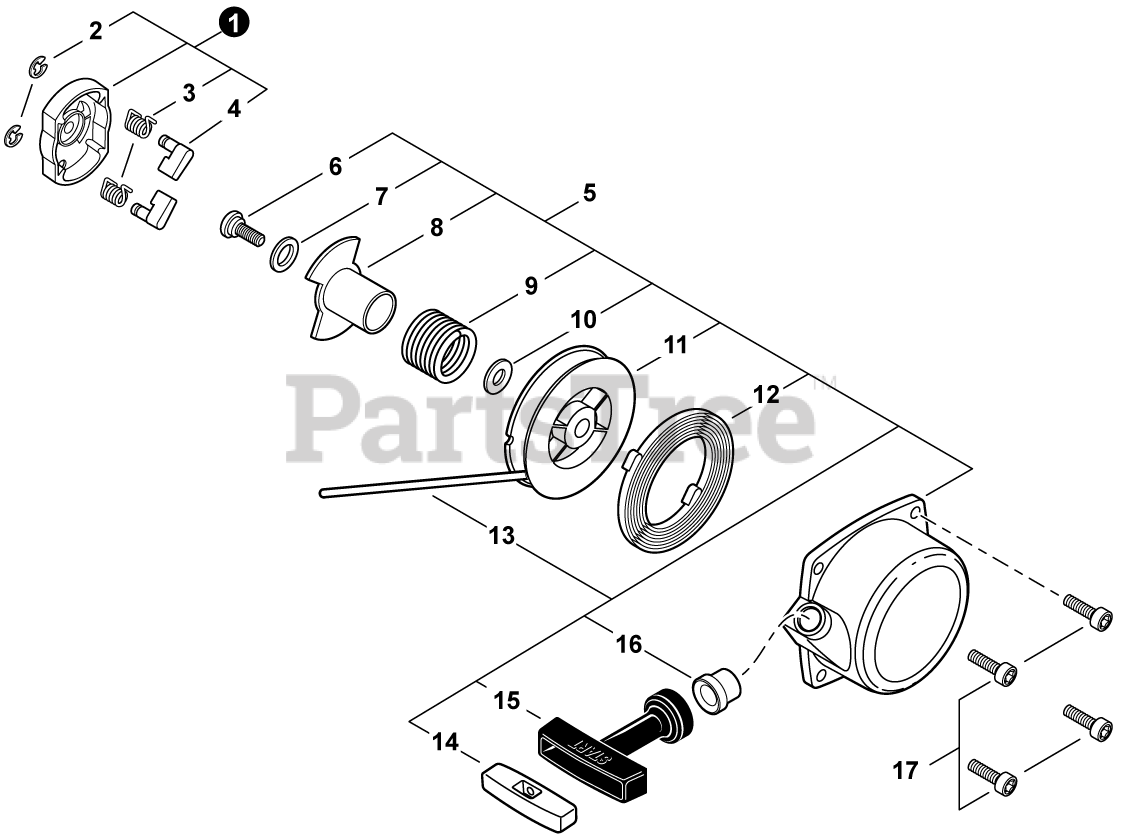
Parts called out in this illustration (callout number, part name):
1	PAWL ASSY, STARTER
2	E-RING 4
3	SPRING, RETURN
4	PAWL, STARTER
5	STARTER ASSY, RECOIL
6	SCREW 5
7	WASHER, THRUST
8	PAWL CATCHER
11	REEL, ROPE
12	SPRING, SPIRAL
13	ROPE, STARTER 3.5x1000 MM
14	RETAINER, ROPE
15	GRIP, STARTER
16	GUIDE, ROPE
17	SCREW 5x16
